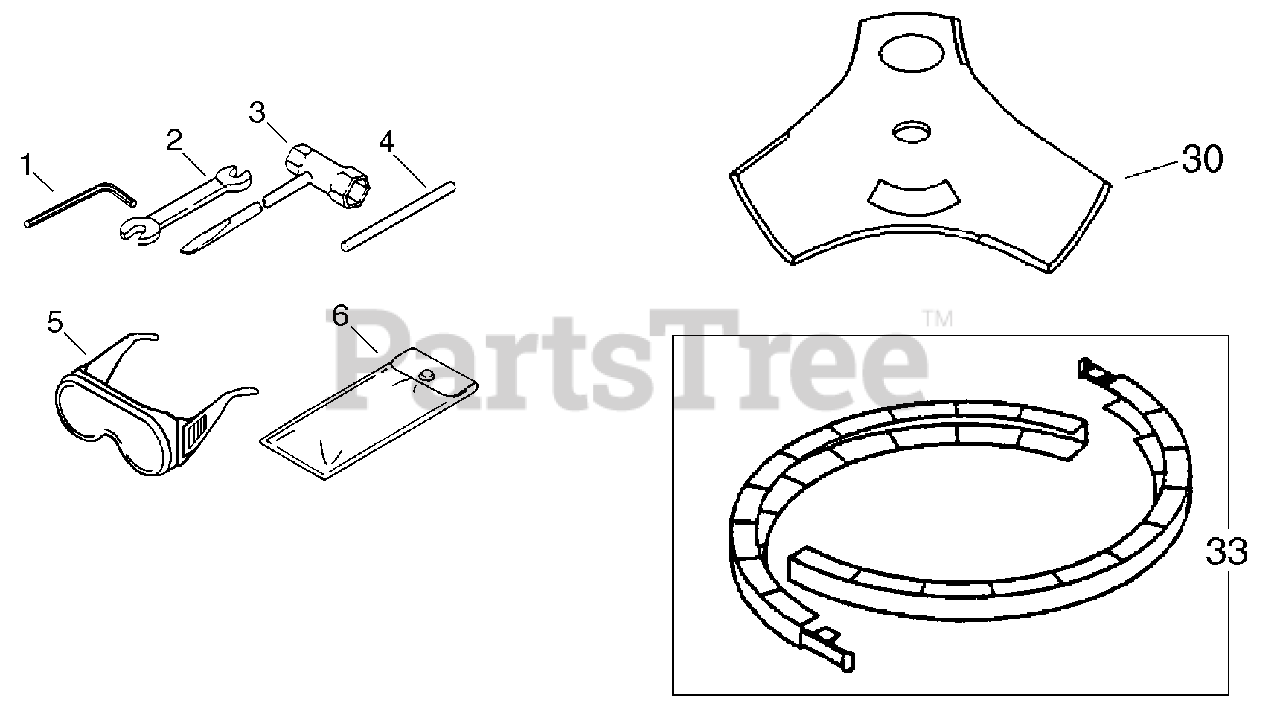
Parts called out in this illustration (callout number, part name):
1	WRENCH, ALLEN 4 MM
2	SPANNER 8×10
3	T-WRENCH 17x-19 L200
4	TOOL, LOCKING 5×120 MM
5	GLASSES, SAFETY
6	BAG, TOOL
30	BLADE, 9" 3-TOOTH
33	SCABBARD
